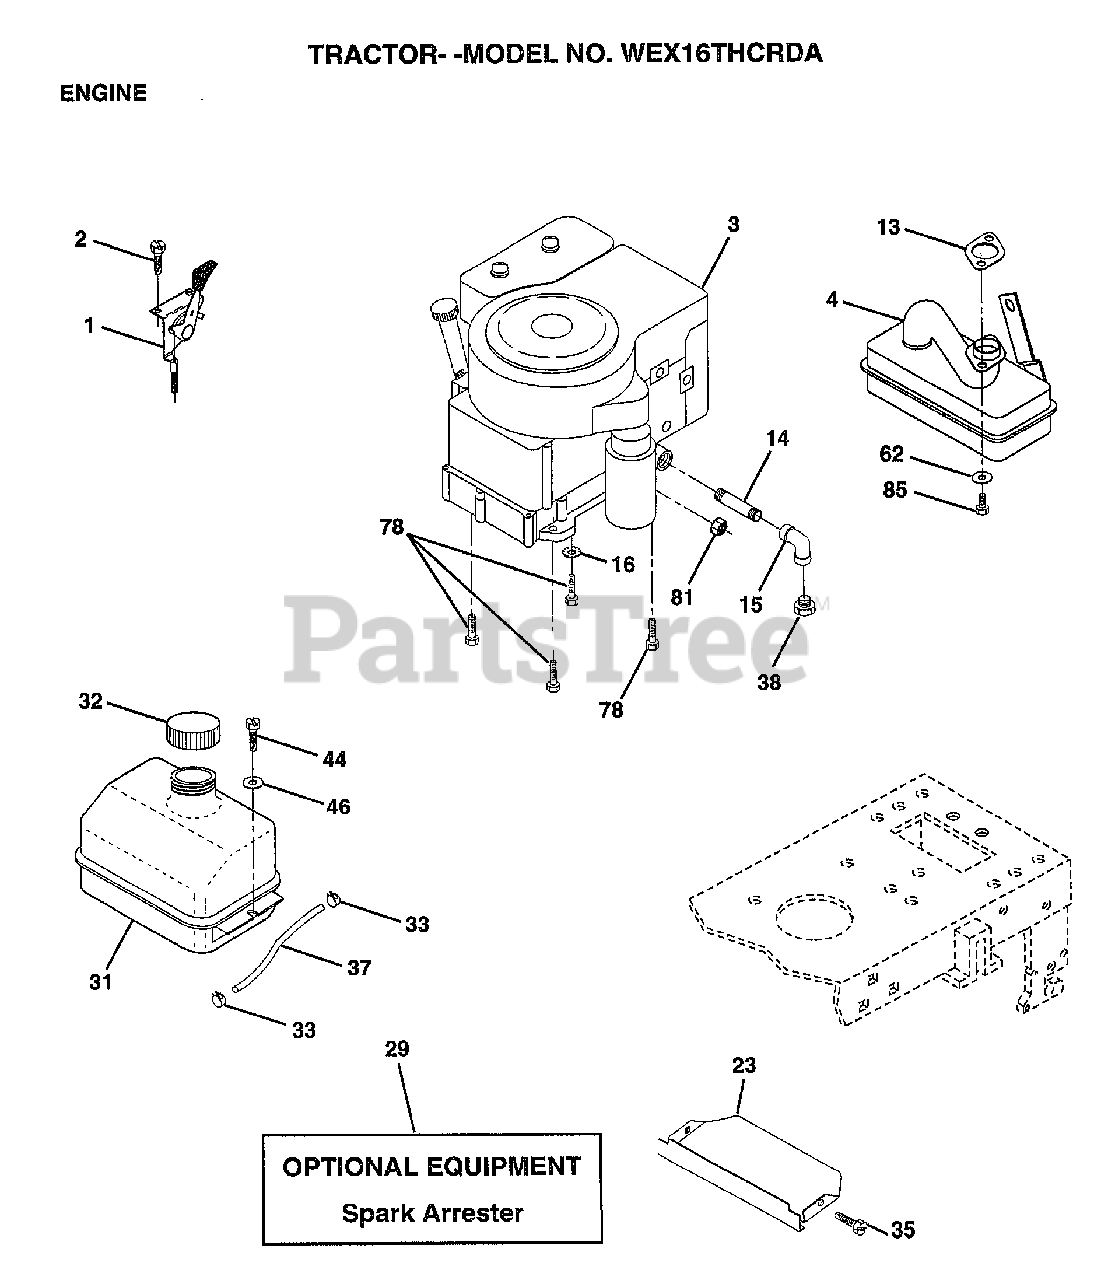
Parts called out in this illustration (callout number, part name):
1	CONTROL THROTTLE
2	SCREW LT
4	MUFFLER
13	GASKET MUFFLE TEC
14	PIPE NIPPLE
15	ELBOW
16	LOCKWASHER
23	SHIELD.BRN/DBR.GD
31	TANK.FUEL.LT.
32	CAP ASM FUEL
33	HOSE CLAMP
35	SCREW
37	LINE FUEL
44	SCREW HEX CRT
46	WASHER
62	LOCKWASHER
78	SCREW
81	NUT
85	SCREW HEX HD CAP
